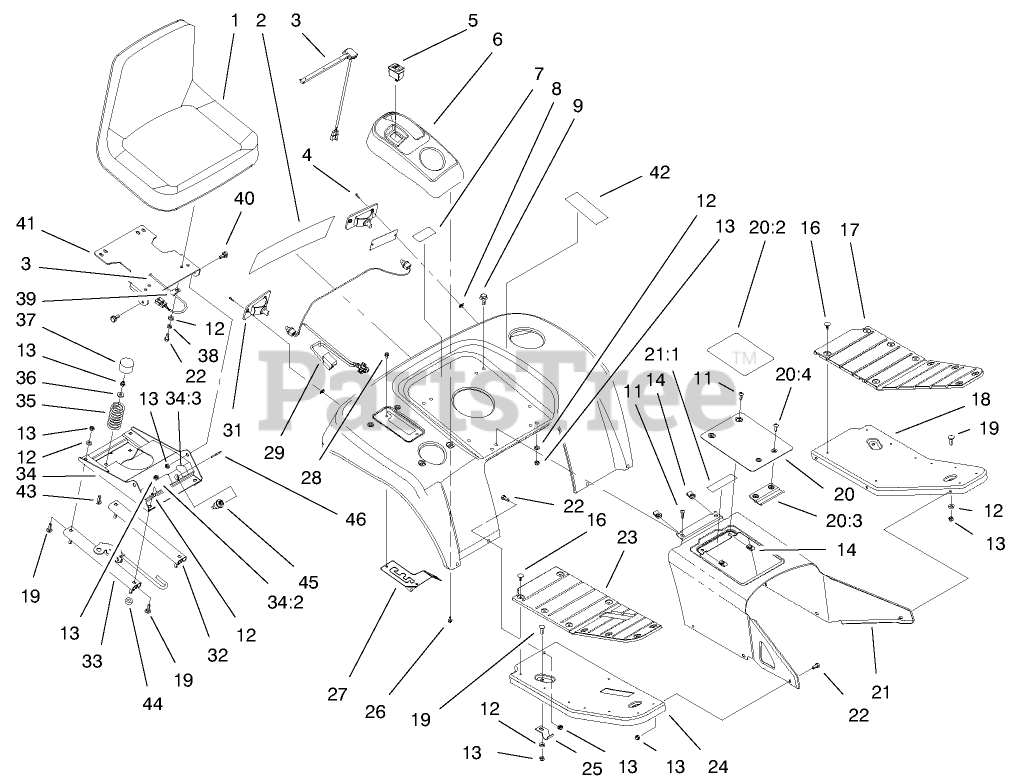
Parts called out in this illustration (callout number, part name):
3	SWITCH-SEAT
4	SCREW-PPH
5	SWITCH-CRUISE
6	POD-CONTROL
6	POD - CONTROL INT'L
7	DECAL - USA
8	NUT-SPEED
9	SCREW-HHF
11	SCREW-HH
12	WASHER-PLAIN
13	NUT-LOCK, NI
16	FASTENER-PANEL
17	PAD-FOOTREST, LH
18	FOOTREST-LH
19	SCREW-CARR
20	TUNNEL COVER ASM
20:2	DECAL-DANGER
20:2	DECAL - DANGER
20:3	RETAINER-COVER
20:4	SCREW-PLASTITE
20:4	SCREW-PPH
21	TUNNEL ASM
21:1	DECAL-DANGER
21:1	DECAL - WARNING
22	SCREW-HH
24	FOOTREST-RH
25	BRACKET-FOOTREST
26	SCREW-HWH
27	GATE-HI / LO SHIFT
28	SCREW-HWH
29	HARNESS-REAR
31	LAMP-TAILLIGHT
32	SLIDE-SLAVE, SEAT
33	SLIDE-LATCH, SEAT
34	SEAT BASE ASM
34:2	DECAL-DANGER
34:3	DECAL-SWITCH, NMIR
35	SPRING-COMPRESSION
36	BUSHING
37	CAP-SPRING, SEAT
38	WASHER-LOCK
39	CLAMP-R
40	BOLT-SHOULDER,HFH
42	DECAL - DIESEL
43	SCREW-CARR
44	WASHER-FLAT
45	STARTER SWITCH ASM
46	KEY-IGNITION
